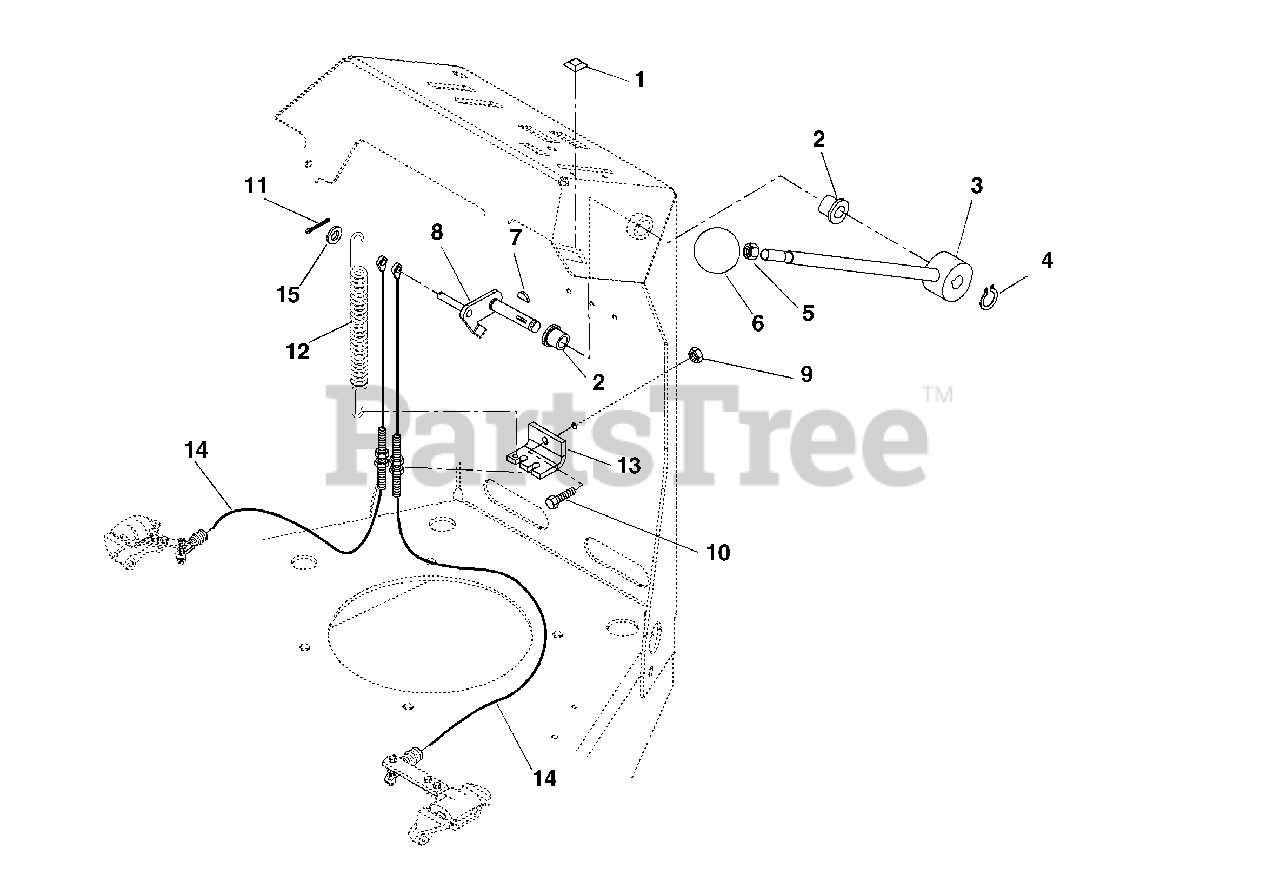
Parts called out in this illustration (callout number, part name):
1	Stop
2	Bushing-Flange .50 x .75 x .75 x 1.00
3	Weldment, Parking Brake Lever
4	Ring-Retaining-External .50 x .05
5	Nut-Hex-Jam .38-16
6	Knob-Steering Lock
7	Key-Woodruff .13 X .63
8	Weldment, Shaft Brake Activation
9	Nut-Locking-Nylon .31-18
10	Bolt-Hex .31-18 x 1.00 Grade 5
11	Pin-Cotter .09 x .75
12	Spring-Tension .062 x .56 x 8.0
13	Bracket, Cable
14	Cable, Parking Brake
15	Washer-Flat-Steel .344 x .688 x .065
